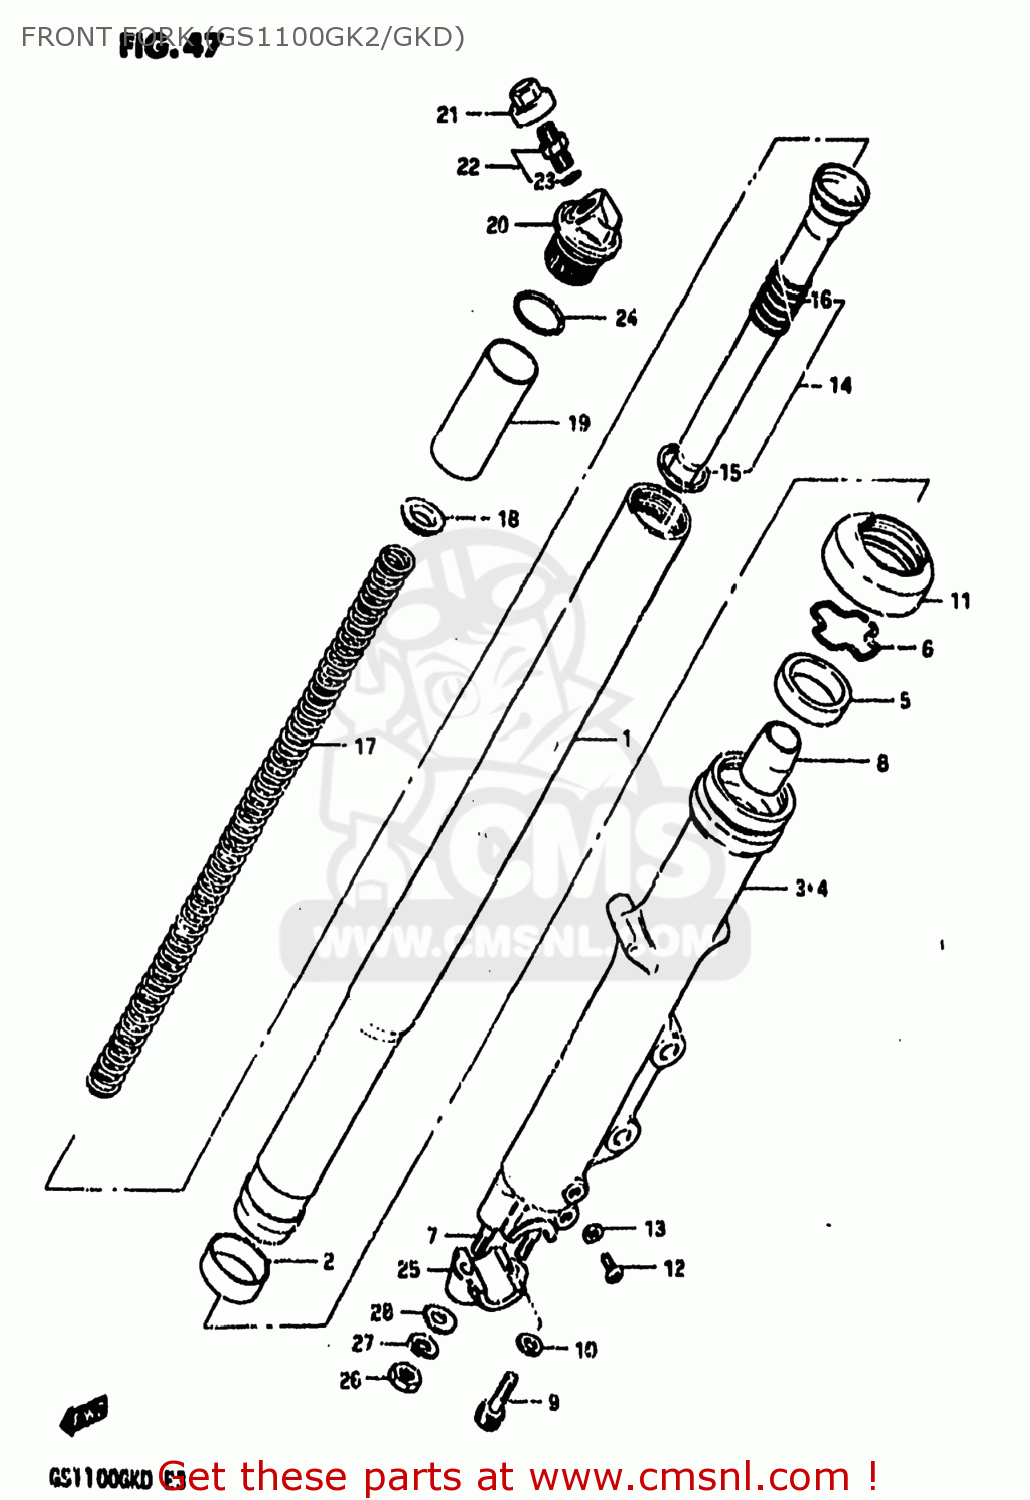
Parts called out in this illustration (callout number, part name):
0	DAMPER ASSEMBLY,LEFT
1	TUBE,FORK,INNER
2	METAL,SLIDE FRONT FORK
3	TUBE,FORK,OUTER,RIGHT
4	TUBE,OUTER,LEFT
5	OIL SEAL,FRONT FORK
6	RING,OIL SEAL STOPPER
7	STUD BOLT
8	PIECE,OIL LOCK
9	BOLT,CYLINDER
10	GASKET,CYLINDER (NAS)
11	SEAL,DUST
12	SCREW
13	GASKET,DRAIN,PLUG (NAS)
14	CYLINDER,FRONT FORK
15	RING,PISTON
16	SPRING,REBOUND
17	SPRING,FRONT FORK
18	GUIDE
19	SPACER,SPRING
20	CAP,FORK INNER TUBE
21	CAP,VALVE
22	VALVE
23	O RING
24	O RING
25	HOLDER,AXLE
26	NUT (8MM)
27	WASHER,LOCK,8.
28	WASHER
